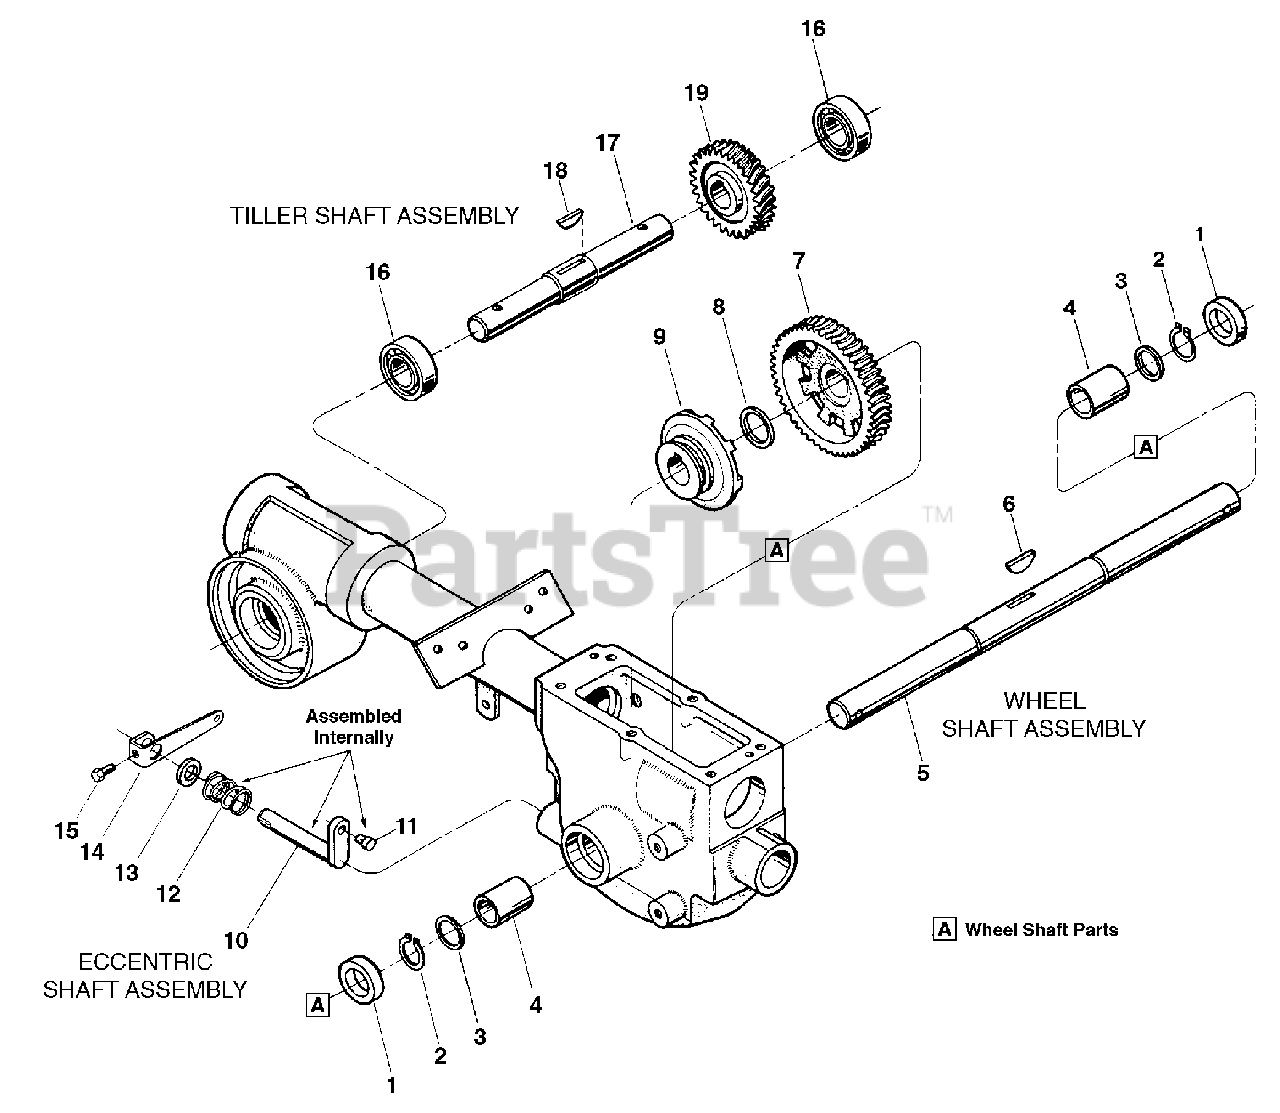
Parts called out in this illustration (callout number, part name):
1	Oil Seal
2	Ring-Retaining, heavy-duty, ext
3	Shim-1-1/64 I.D., .062 thick
4	Bushing
5	Wheel Shaft (axle)
6	Key-Hi-Pro, 1/4 x 1-5/16
7	Gear-Wheel drive (worm gear)
8	Shim-1.016 I.D. x 1.468 O.D. x .062 thick
9	Clutch-Wheel drive, cast iron
10	Eccentric Shaft-Wheel clutch
11	Pin-Eccentric shaft
13	Oil Seal-Eccentric shaft
14	Lever-Eccentric shaft
15	Hex Hd. Screw, 1/4-20 x 1/2
16	Ball Bearing
17	Tiller Shaft
18	Key-Woodruff, 1/4 x 1-1/4
19	Worm Gear-bronze, tiller drive
